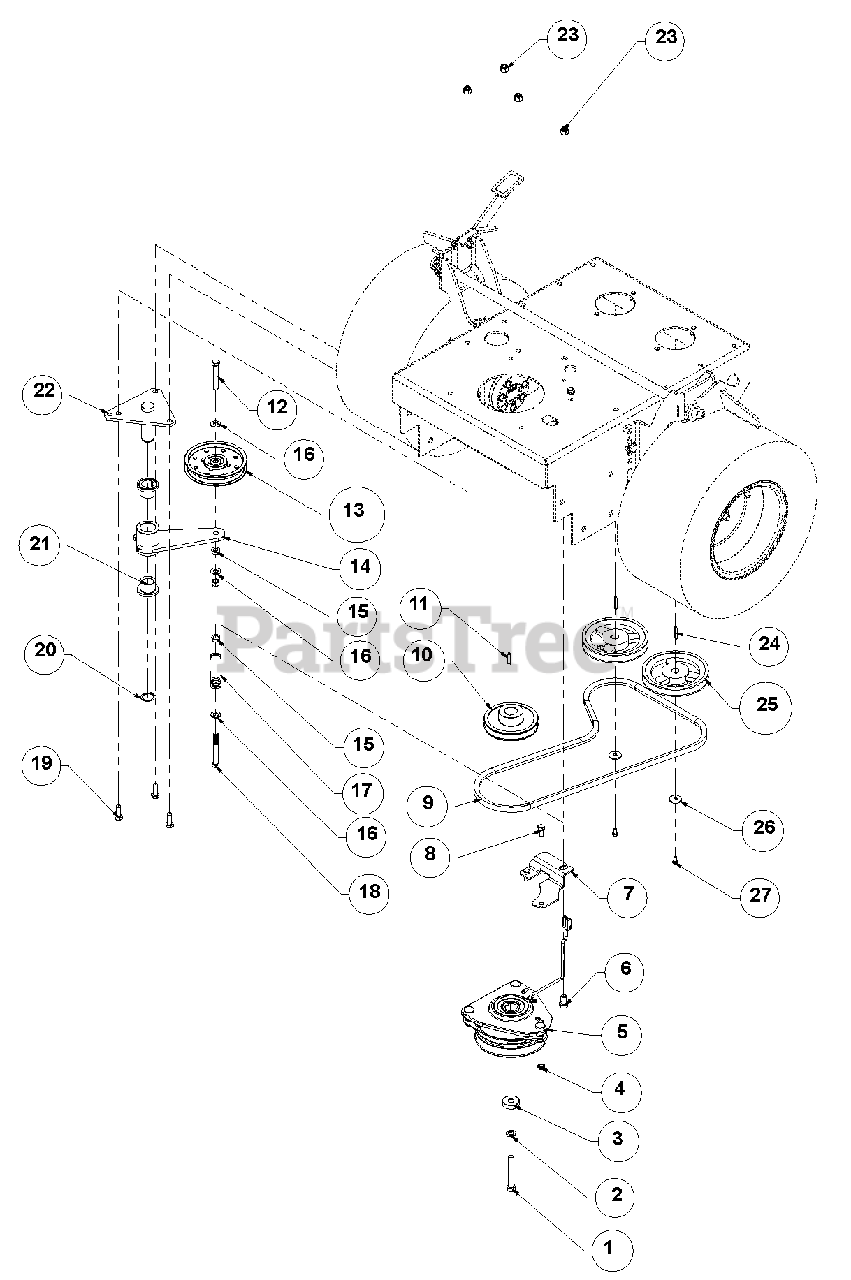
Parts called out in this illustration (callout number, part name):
1	Bolt, .4375-20 x 3.00 Hex 5
2	Washer, .438 Medium Spring Lock
3	Spacer, .468 x 1.38 x .375
4	Locknut, .3125-18 Nyloc
5	Clutch Assembly, OGURA
6	Bolt, .4375-14 x .750 Hex 5
7	Plate, Clutch Dog
8	Bolt, .3125-18 x .750 Hex 5
9	Belt, HA 55.1 Elbow AMD OHR
10	Pulley, V-Belt 4.45 x 1.00 with Key
11	Key, .250 x .250 x .995 TPR
12	Bolt, .38-16 x 2.50 Hex 5
13	Pulley, Flat 4.50 x .375 W/BRG
14	Weldment, Idler Arm
15	Locknut, .38-16 Whiz
16	Washer, .406 x .813 x .065 Flat
17	Spring, External .900 x .135 x 4.50
18	Bolt, .38-16 x 3.00 Hex 8
19	Bolt, .38-16 x 1.00 Hex 5
20	Snap Ring, 1.00 x .042 External
21	Bearing, Flange 1.00 x 1.25 x 1.00
22	Weldment, Idler Pivot Mount
23	Locknut, .38-16 Nyloc
24	Key, M5 x M5 x M30 RD
25	Assembly, Pump Pulley w/Set Screw
26	Washer, .250 Wide Heavy Flat
27	Bolt, M6 x 1.00 x 10 Hex 8.8
